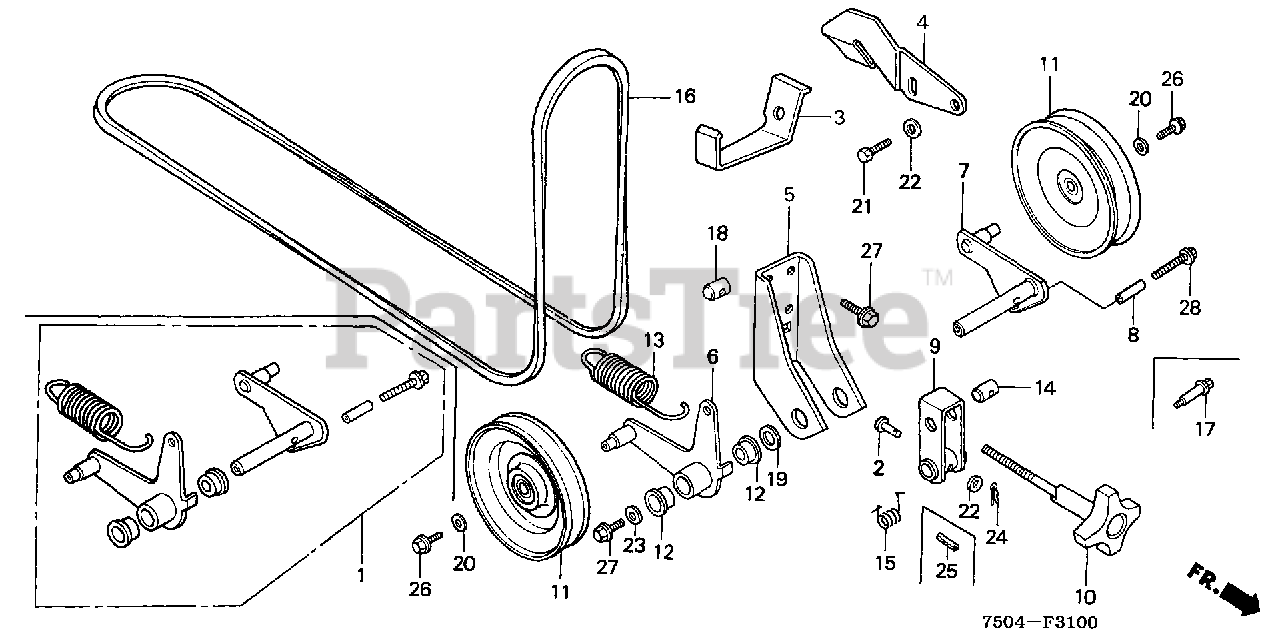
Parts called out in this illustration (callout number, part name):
2	PIN, ROLLER (6MM) (SOURCE: VINTAGE PARTS INC.)
2	PIN (6X25)
3	STOPPER, BELT DRIVEN
5	BRACKET, TENSIONER
6	ARM, TENSIONER (1)
7	ARM, TENSIONER (2)
8	COLLAR, BELT STOPPER
9	LEVER, TENSIONER
10	KNOB, TENSIONER
11	PULLEY, TENSIONER
12	BUSH (17X23X19)
13	SPRING, TENSIONER
14	PIN, TENSIONER
16	V-BELT, DECK
17	BOLT, P.T.O. CLUTCH LEVER
18	NUT, TENSIONER
19	COLLAR, TENSIONER BRACKET
20	WASHER, SHIFT DRUM STOPPER
22	WASHER, PLAIN (6MM)
23	WASHER (8.5MM)
24	PIN, LOCK (6MM)
26	BOLT, FLANGE (6X16)
27	BOLT, FLANGE (8X14)
28	BOLT, FLANGE (8X55)
